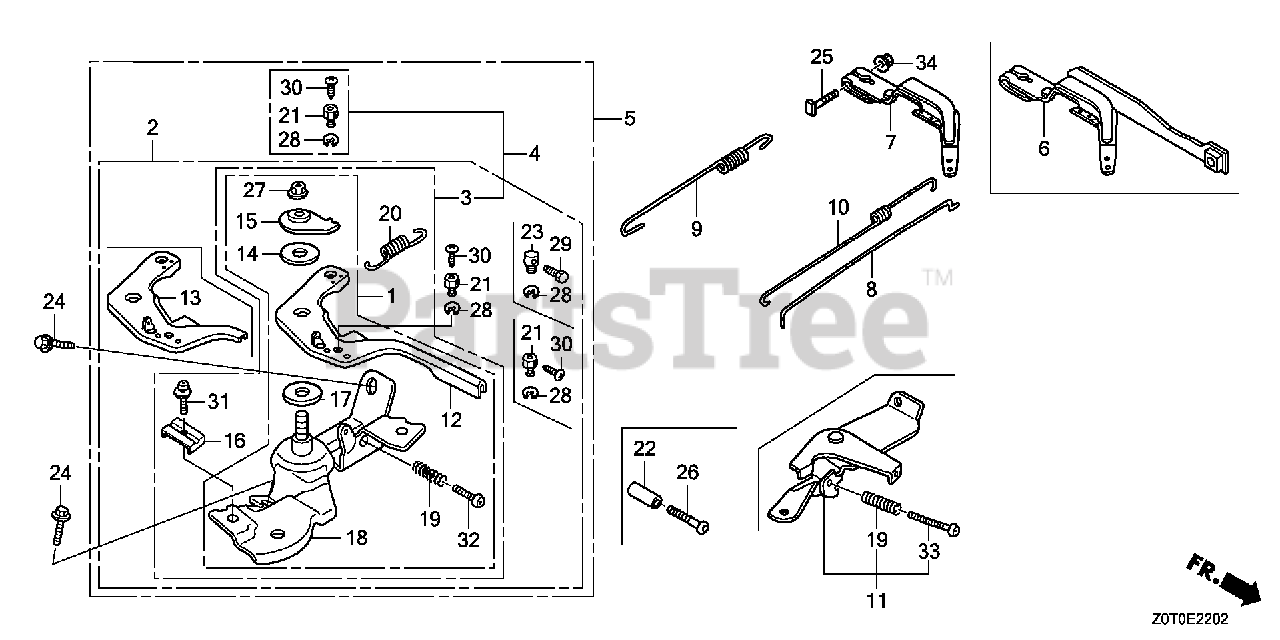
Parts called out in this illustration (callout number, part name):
7	ARM, GOVERNOR
8	ROD, GOVERNOR
9	SPRING, GOVERNOR
10	SPRING, THROTTLE RETURN
11	CONTROL ASSY. (COO)(FOR U.S.A.)
19	SPRING, CONTROL ADJUSTING
24	BOLT, FLANGE (6X12) (CT200)
25	BOLT, GOVERNOR ARM
33	SCREW, PAN (5X40)
34	NUT, FLANGE (6MM)
